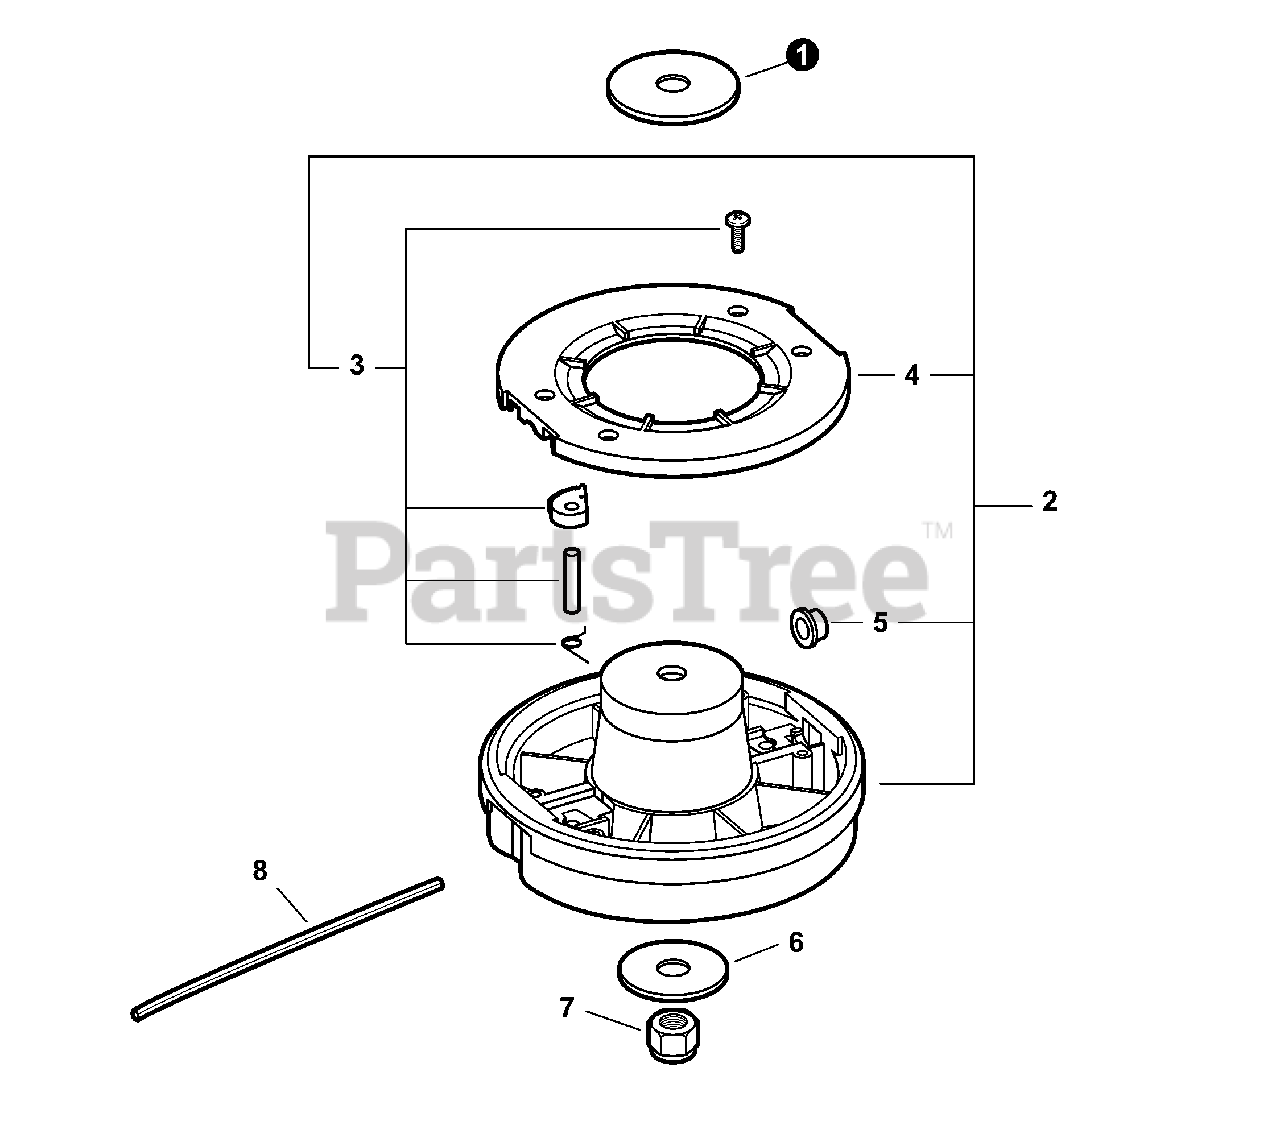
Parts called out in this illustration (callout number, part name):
2	TRIMMER HEAD, RAPID-LOADERT- 2 LINE
3	PAWL KIT
4	COVER, TOP
5	EYELET (PACKAGE OF 3)
6	WASHER 10
7	NUT, LOCK
8	LINE, TRIMMER - 0.080 DIA. (PKG. OF 20)
